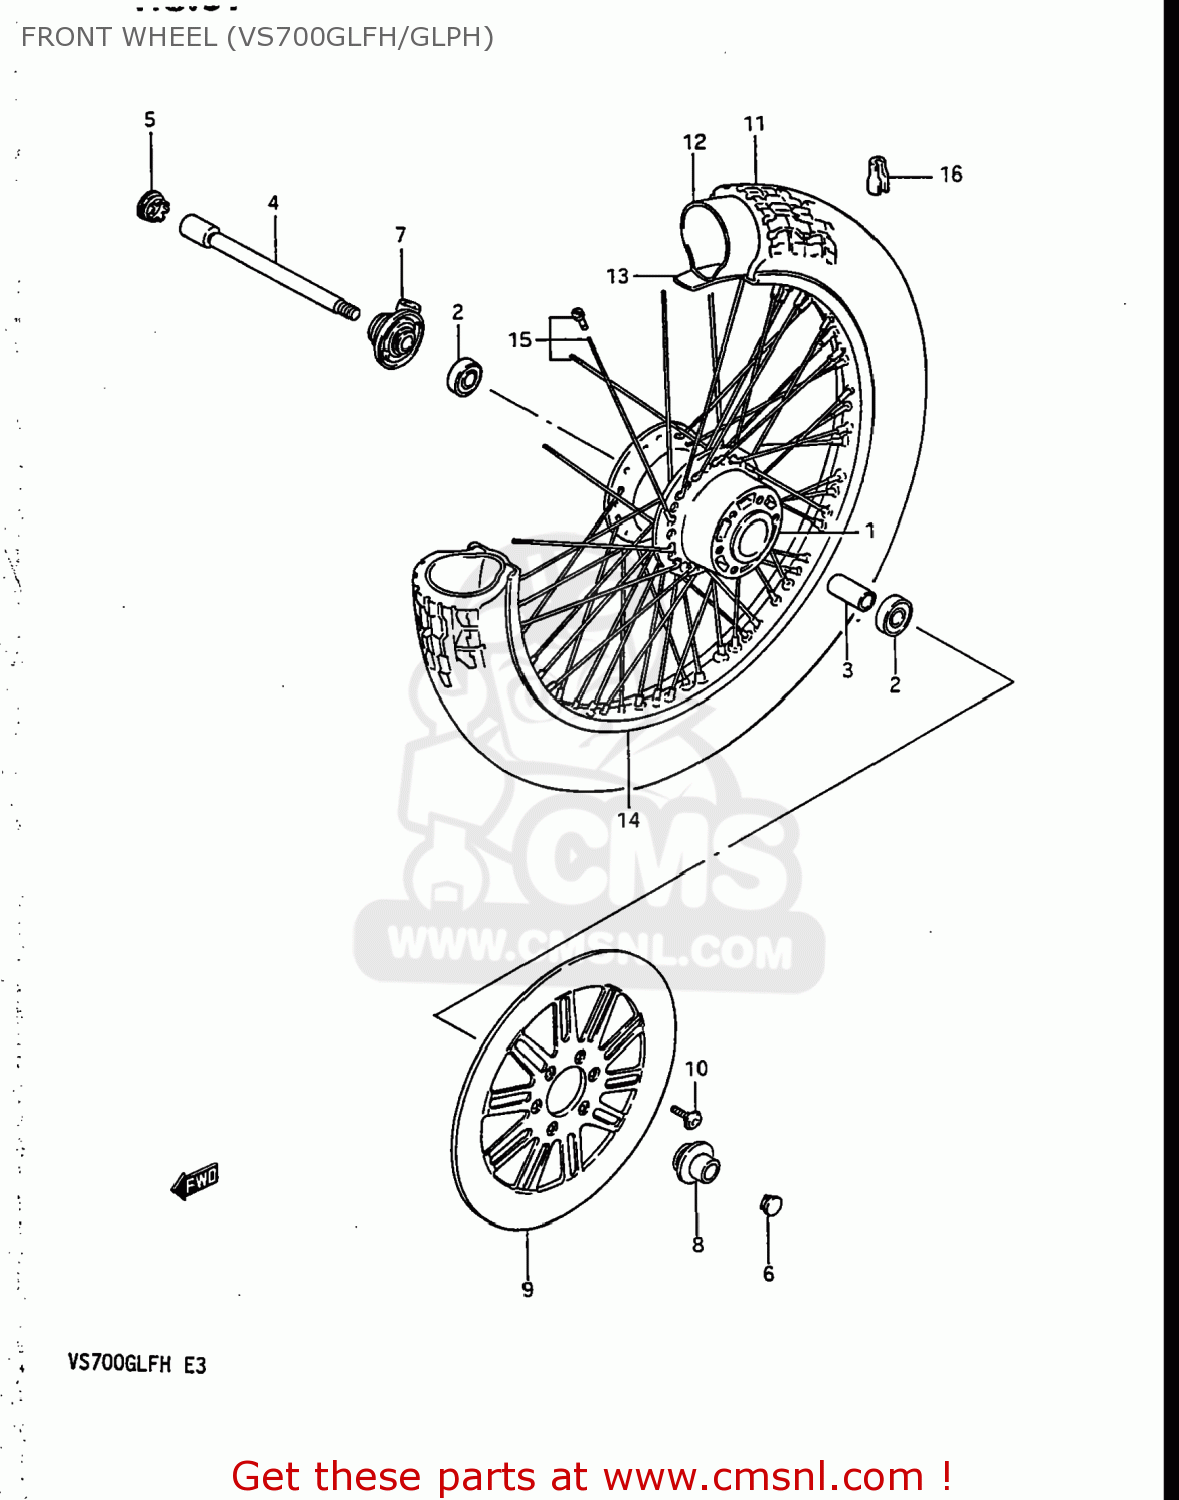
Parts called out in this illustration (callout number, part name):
1	HUB ASSY,FR
2	BEARING
3	SPACER(15.3X21.7X65)
4	AXLE,FRONT
5	CAP,FR AXLE
6	CAP,FRONT AXLE
7	BOX ASSY,SPEEDOMETER GEAR
8	SPACER COMP,FRONT AXLE
9	DISC,FR BRAKE
10	BOLT(8X25.5)
11	TIRE,FRONT
12	TUBE,INNER
13	PROTECTOR,WHL INR TUBE
14	RIM,FRONT WHEEL (MT2.15)
15	SPOKE SET,FR WHEEL
16	BALANCER,WHEEL
